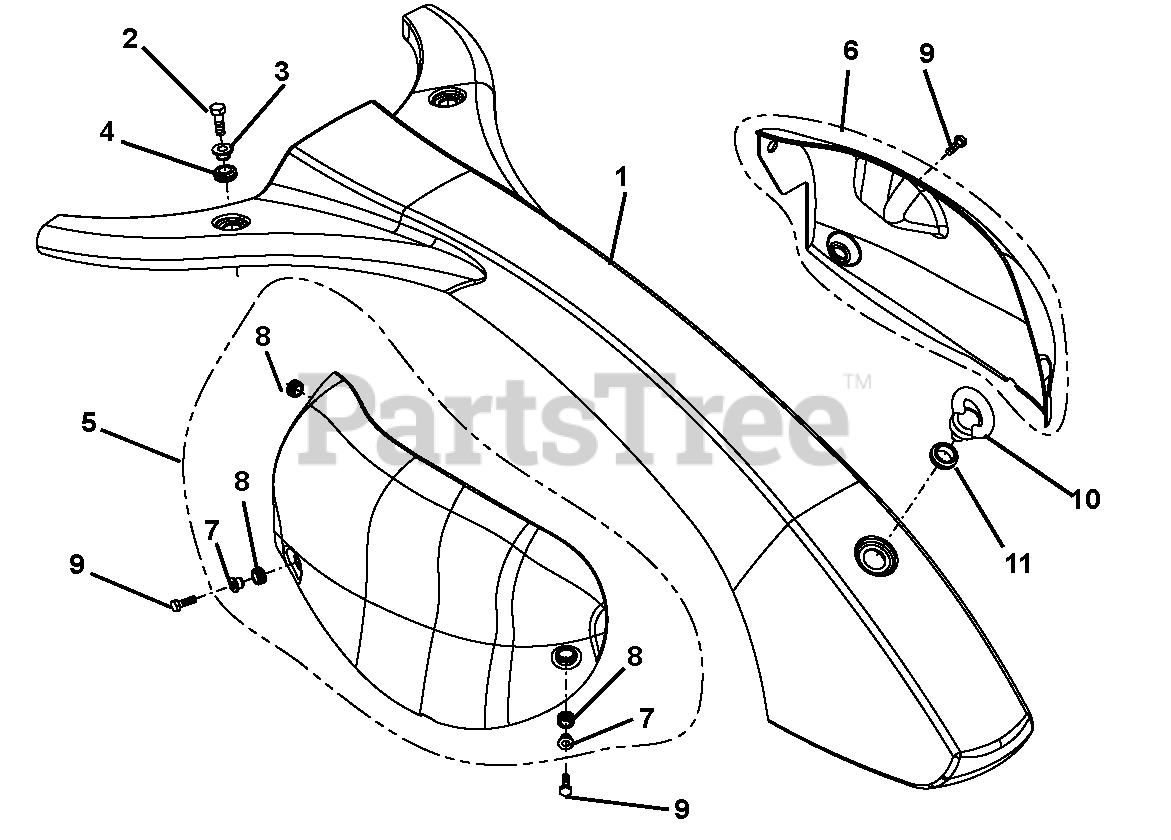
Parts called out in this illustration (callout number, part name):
1	Bonnet Handlebar
2	Bolt, Hex D933 M8 x 25
5	Bonnet Assembly (Includes 7 & 8)
6	Bonnet Assembly (Includes 7 & 8)
9	Bolt, Hex D933 M6 x 20
10	Screw, Ring D580 M12 x 20
11	Grommet, N553 18 x 27 x 22
